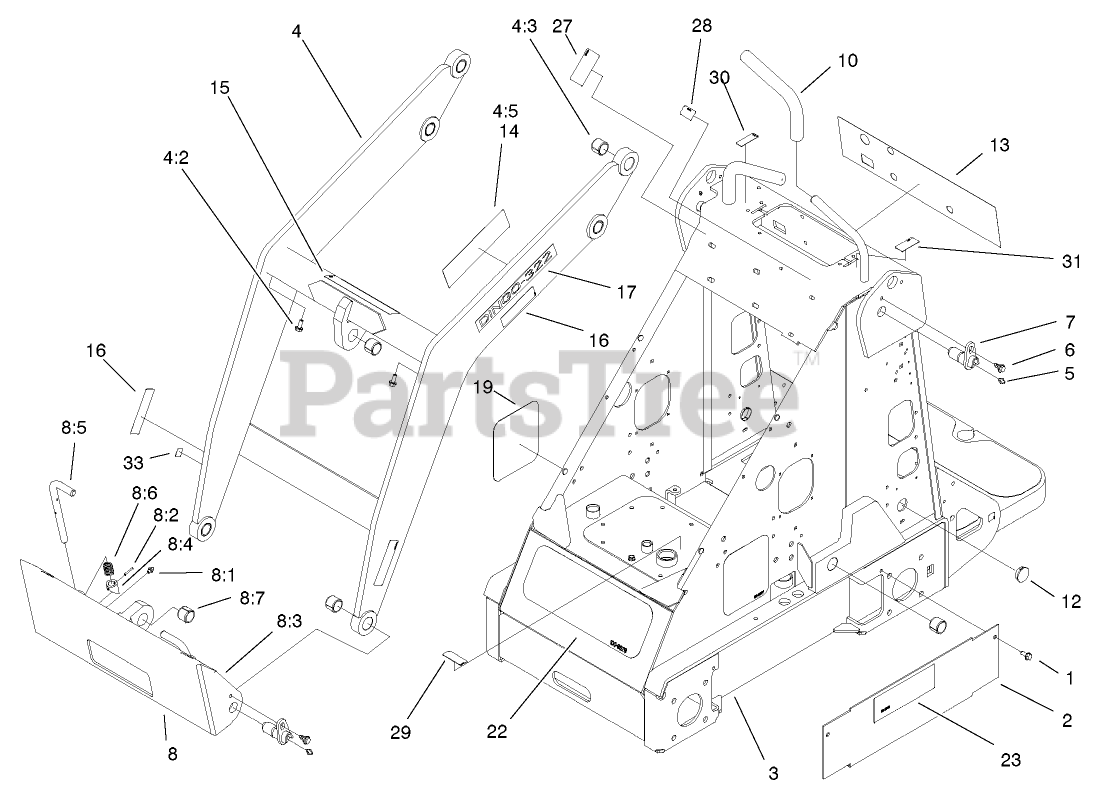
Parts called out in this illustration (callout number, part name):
1	SCREW-HWHTF
2	Cover-Hose (only on: 22305)
3	FRAME ASM
4	LOADER ASM
4:2	SCREW-HWHTF
4:3	BUSHING-TENSION
4:5	DECAL-DANGER
5	FITTING-GREASE
6	BOLT-SHOULDER
7	PIN-PIVOT
8	QUICK ATTACH ASM
8:1	FITTING-GREASE
8:2	PIN-SPECIAL
8:3	MOUNT-ATTACH, QUICK
8:4	CAM-ATTACH, QUICK
8:6	SPRING-COMPRESSION
8:7	BUSHING-TENSION
10	GRIP-CUSHION
12	PLUG-HOLE
13	DECAL-PANEL, CONTROL
14	DECAL-DANGER
15	DECAL-CAUTION
16	DECAL-PINCH
17	DECAL - DINGO 322
19	Decal-Dingo, Side (only on: 22305)
22	DECAL-DINGO, FRONT
23	DECAL-4-PAW
27	DECAL-POWER, AUXILIARY
28	DECAL-LIMITER, SPEED
29	DECAL-ONLY, HYD OIL
30	DECAL-CHOKE
31	DECAL-THROTTLE
